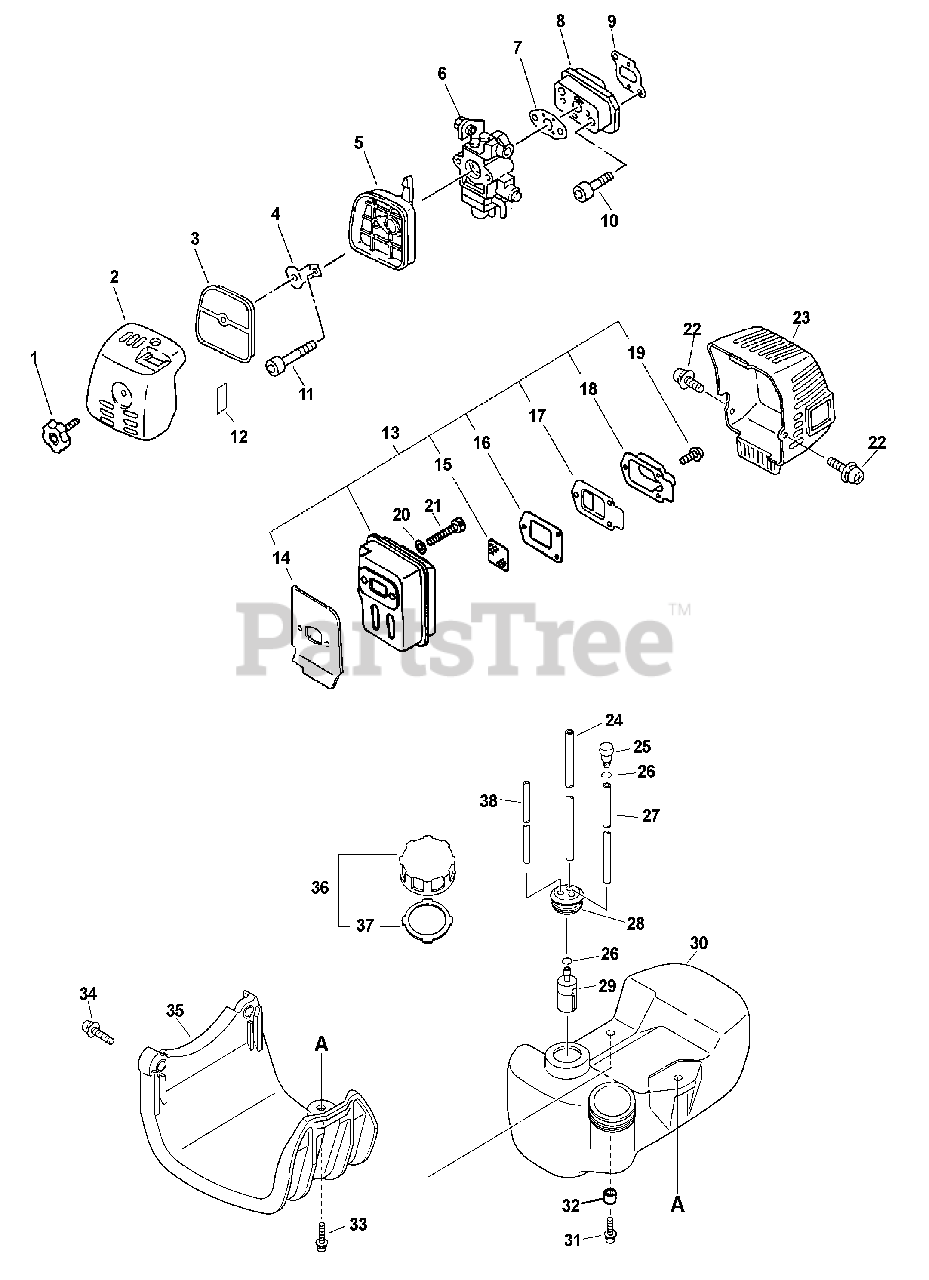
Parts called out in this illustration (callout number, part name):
1	THUMBSCREW
2	COVER, AIR FILTER
3	FILTER, AIR - HEAVY DUTY
4	PLATE, PREVENT
5	CASE, AIR FILTER
6	CARBURETOR WYJ-192
7	GASKET, INTAKE
8	INSULATOR, INTAKE
9	GASKET, INTAKE
10	SCREW - 5X25
11	SCREW - 5X55
12	LABEL - CHOKE
13	MUFFLER ASSY
14	SHIELD, EXHAUST
15	SCREEN, SPARK ARRESTOR
16	GASKET, EXHAUST
17	GASKET, EXHAUST - INNER
18	GUIDE, EXHAUST - OUTER
19	SCREW - 4X10
20	WASHER - 5
21	SCREW - 5X55
22	SCREW - 5X12
23	COVER, EXHAUST
24	PIPE - 3X6X170 -- BLACK
25	VENT, FUEL TANK
26	CLIP - 6.5
27	PIPE - 3X6X100 -- BLACK
28	GROMMET
29	FILTER, FUEL
30	TANK, FUEL
31	SCREW - 5X16
33	SCREW - 5X20
34	SCREW - 5X22
35	GUARD, FUEL TANK
36	CAP ASSY
37	GASKET, CAP
38	PIPE - 3X6X60 -- CLEAR
